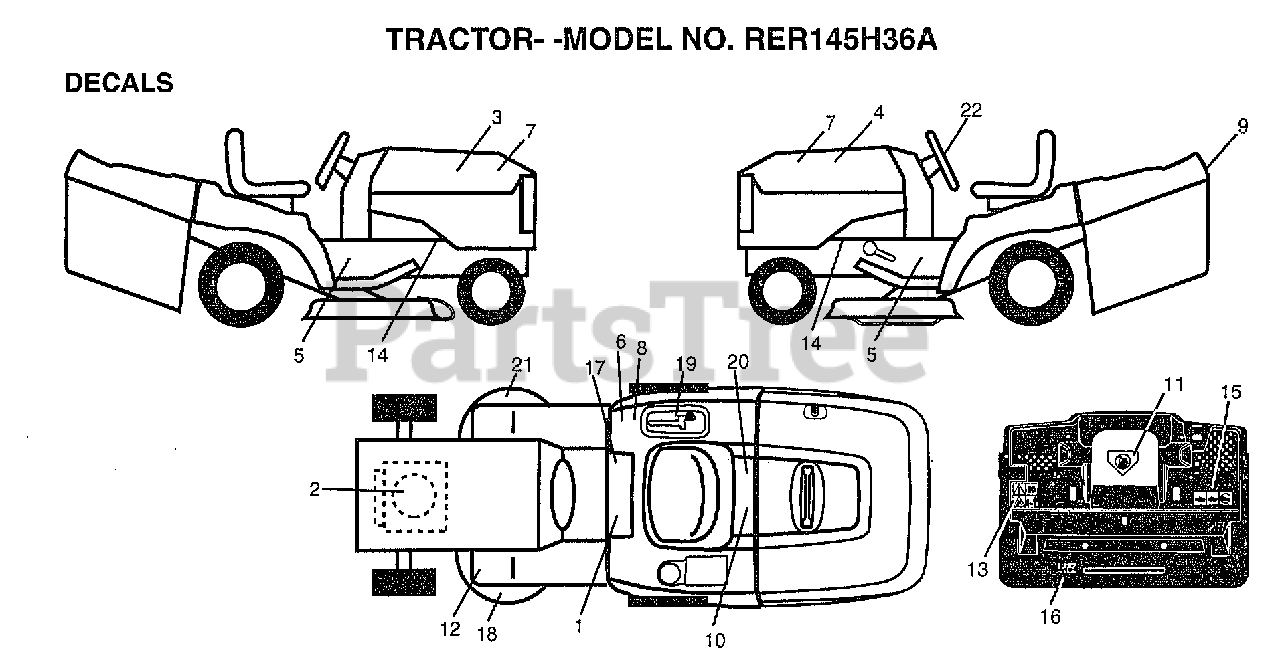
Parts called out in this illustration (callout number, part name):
1	DECAL.READ.O.MANU
2	DECAL.ENGINE
3	DECAL HOOD RH
4	DECAL HOOD LH
5	DECAL.CHASSIS.HYDRO
7	DECAL.INS.HD.RALL
8	DECAL.EURO.ST.CE.
9	FENDER DECAL
10	DECAL.BATRY.3-3908
11	DECAL.DANGER.CUTF
12	DECAL-BRAKE/CLUTC
13	DECAL.WARNING.BACKPLATE.CRD
14	"DECAL CHASSIS,HOT"
15	DECAL, OPER BAG
16	DECAL.DRAWBAR.LDL
17	DECAL BRAK PARK
19	DECAL.BYPASS.FENDER.CRD.
20	DECAL.BYPASS.FENDER.CRD.LT.YT
21	DECAL.DECK.HEX.BELT
22	"DECAL,STR WHL"
